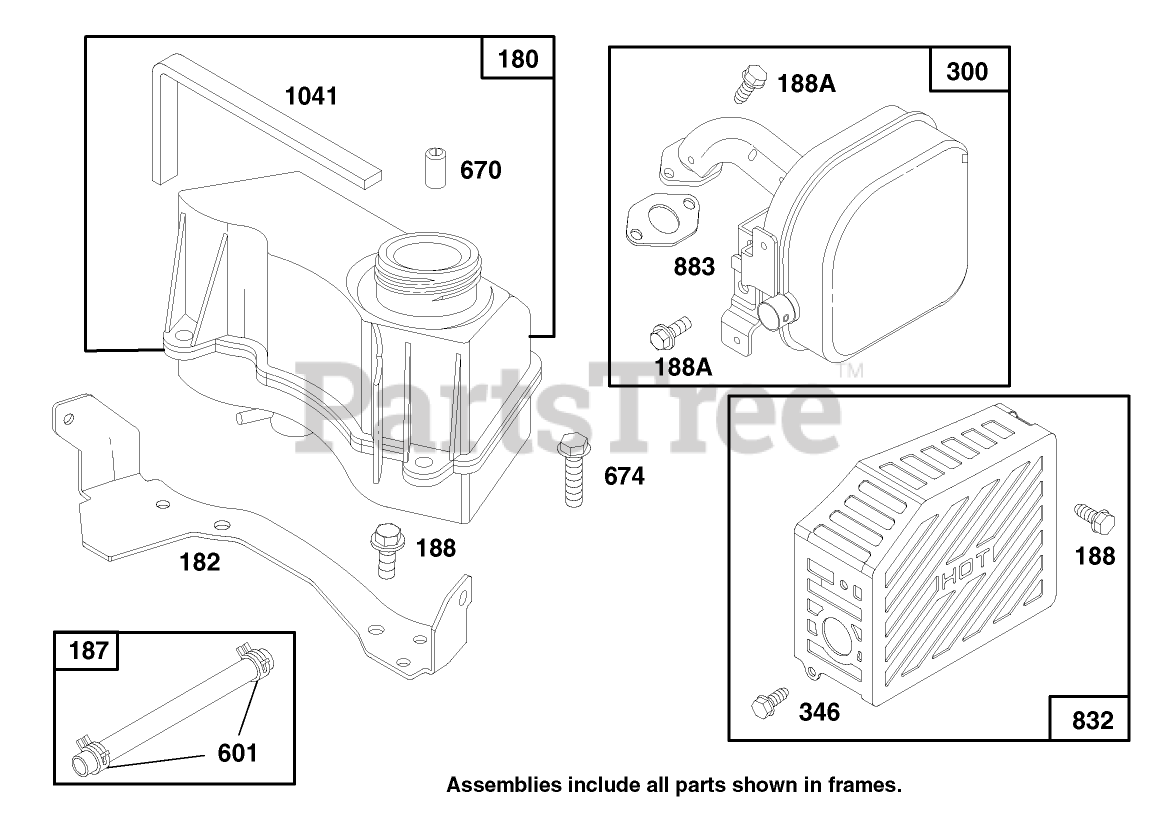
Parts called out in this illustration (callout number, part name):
180	TANK ASSY - FUEL
187	BRIGGS 296004
188	SCREW - HEX HEAD
300	MUFFLER - EXHAUST
670	SPACER
674	SCREW - HEX HEAD
